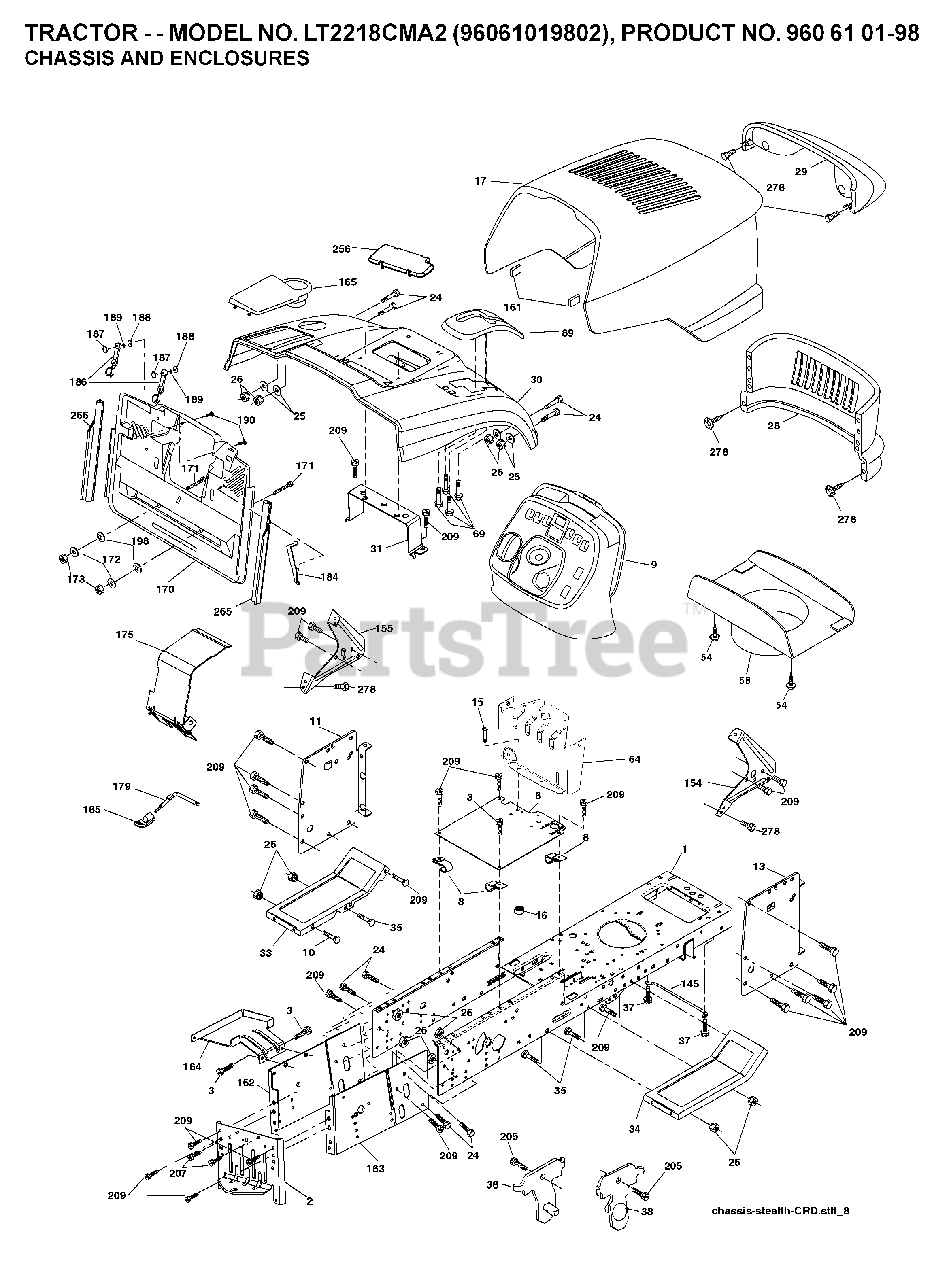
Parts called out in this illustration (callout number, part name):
1	CHASSIS
3	SCREW 3/8-16X3/4
8	CLIP,INSULATOR
10	BOLT D
13	PANEL DASH RH
16	NUT
25	WASHER
26	NUT
31	BRACKET SUPPORT FENDER
54	SCREW.WSHD.HEX10-32X5/8
58	DUCT HOOD
69	SCREW.HI-LO.CONSOLE
145	ROD.PIVOT.HOOD
161	EXTRUSION BUMPER
164	SUPPORT
171	BOLT
172	WASHER
186	LATCH ASSY
187	WELDNUT
189	LOCKWASHER
207	SCREW, 5/16-18 X 1/2
209	SCREW, 3/8-16X3/4
278	SCREW
